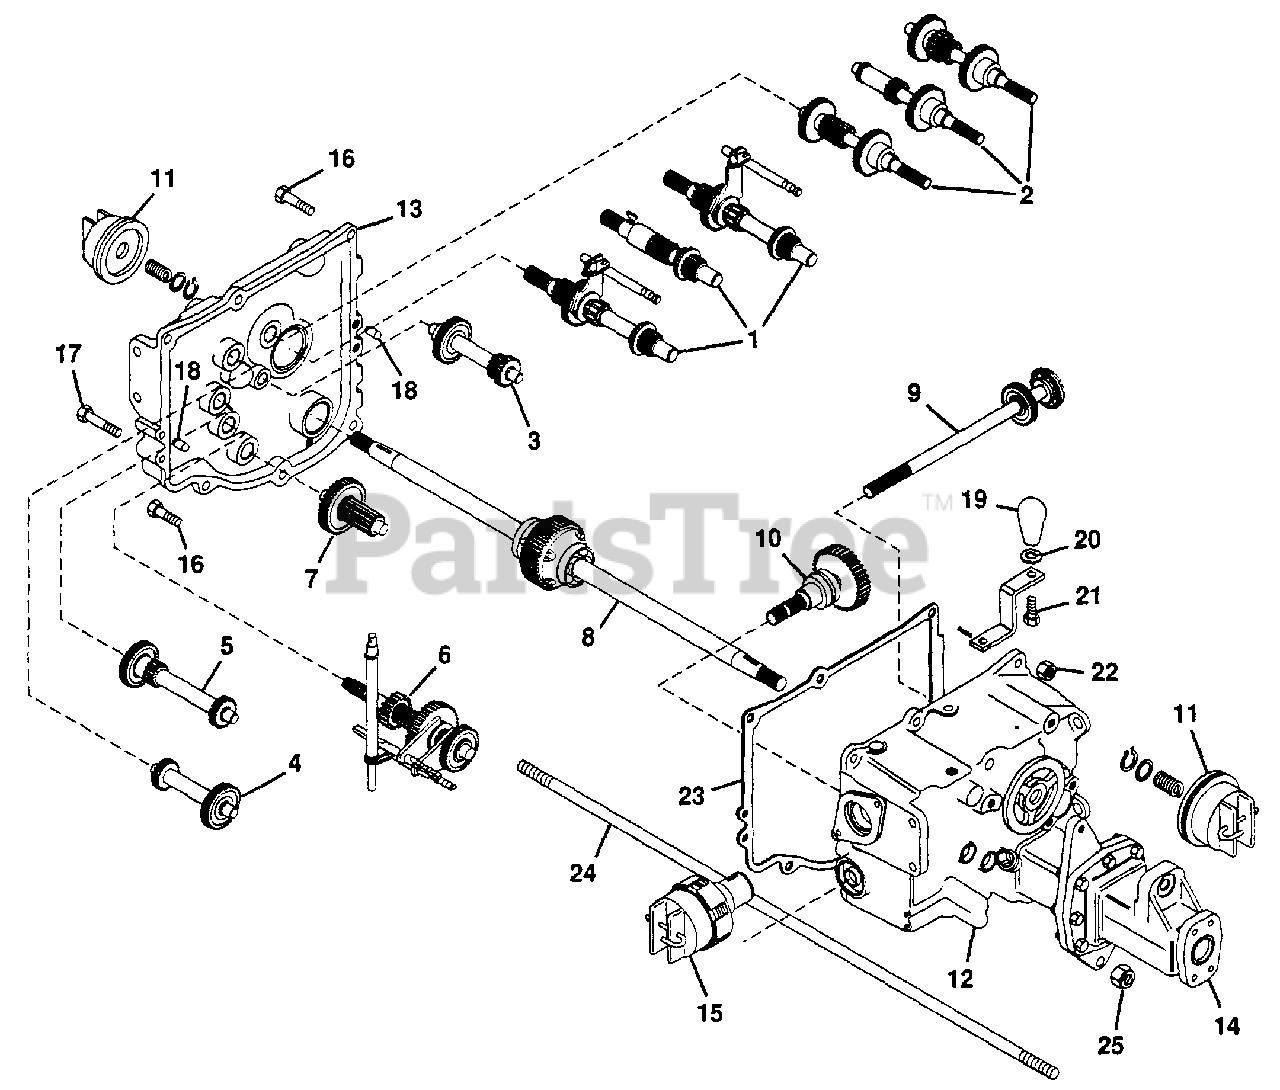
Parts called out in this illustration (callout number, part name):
1	No. 1 Shaft, Forward Clutch
2	No. 2 Shaft, Reverse Clutch
3	No. 3 Shaft, 3rd and 4th Gear
4	No. 4 Shaft, Idler
5	No. 5 Shaft, 1st and 2nd Gear
6	No. 6 Shaft, Brake-Sliding Gear
7	No. 7 Shaft, Pinion-Final Drive
8	No. 8 Shaft, Differential Asm.
9	No. 9 Shaft, PTO Clutch
10	No. 10 Shaft, PTO Drive Asm.
11	No. 11, Fwd-Rev Clutch Asm.
12	No. 12, Transmission Case Asm.
13	No. 13, Transmission Cover Asm.
14	No. 14, Axle Housing
15	No. 15, PTO Clutch Asm.
16	Bolt, Hex 3/8-16x1.50
17	Bolt, Hex 3/8-16x2.25
18	Pin, Dowel .375x.625
19	Knob, Control
20	Washer, Lock 1/2 Reg.
21	Bolt, Hex 1/2-13x.875
22	Nut, Lock 3/8-16
23	Gasket, Transmission Cover
24	Rod, Strut
25	Nut, Lock 1/2-13
